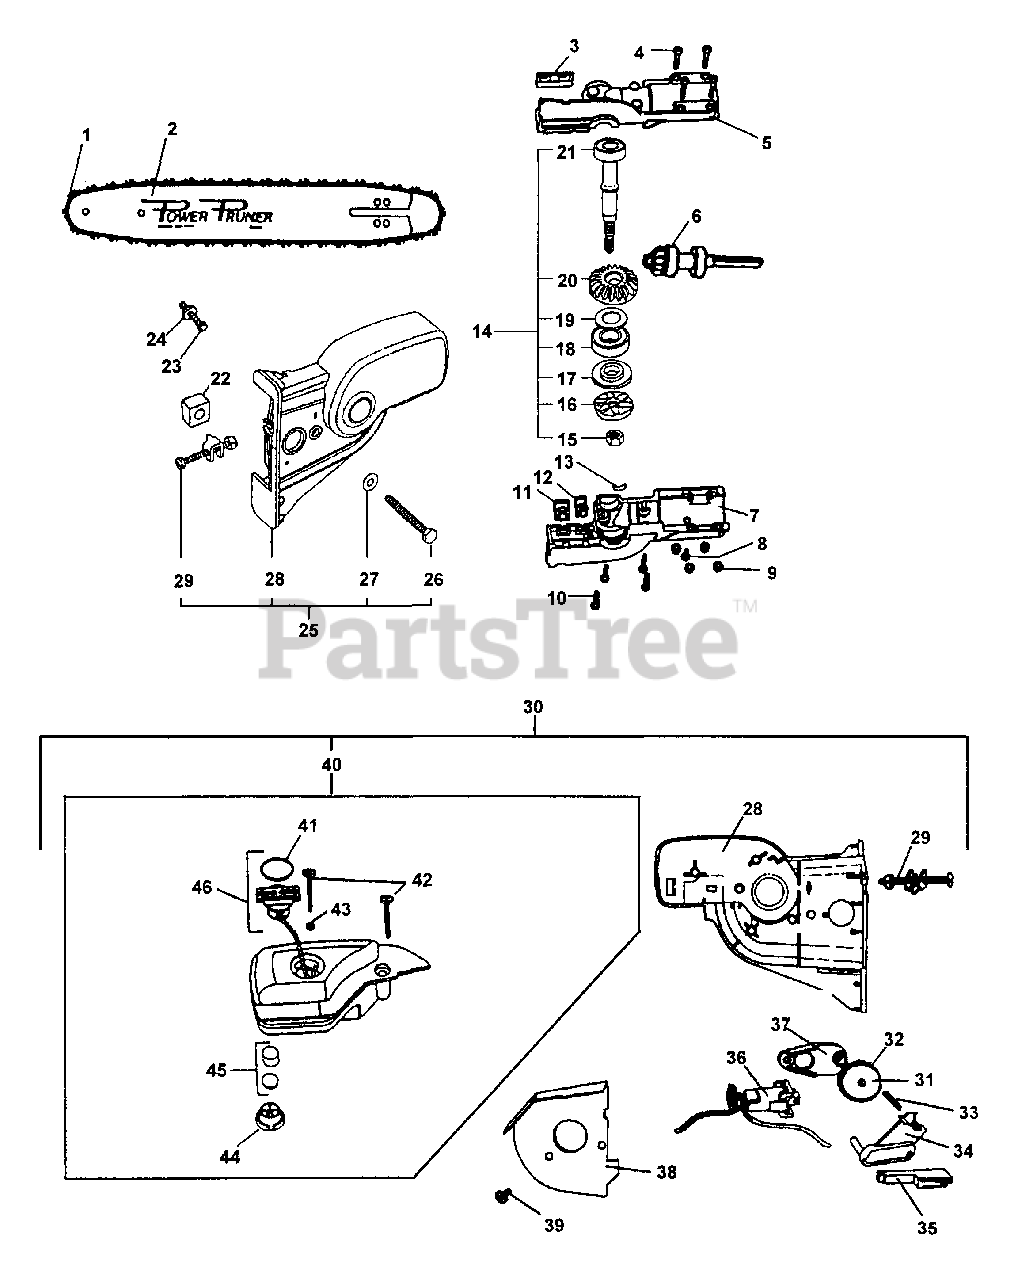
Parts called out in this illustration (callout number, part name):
1	SAW CHAIN
2	GUIDE BAR
4	SCREW, TORX 10-24 UNC 1-1/4
5	CASE, GEAR
6	SHAFT GEAR ASSY
7	CASE, GEAR
8	SCREW
9	NUT, LOCK 10-24 UNC
10	SCREW, TORX
11	SPACER
14	GEAR SHAFT ASSY
15	NUT, HEX
16	SPROCKET, DRIVE
17	SPACER, SPROCKET
18	BEARING, BALL 6001 DDU
19	WASHER 12
20	GEAR, BEVEL
21	SHAFT, GEAR
22	SPACER
23	SCREW
24	WASHER 6
25	OILER COVER ASSY
27	WASHER, FLAT
28	COVER, OILER
29	TENSIONER ASSY, CHAIN
30	AUTO-OILER ASSY
31	CAM, OIL PUMP
33	SPRING, COMPRESSION
34	LINK, OILER IDLER
36	AUTO-OILER ASSY
37	LINK, OILER DRIVE
38	PLATE, PROTECTION
39	SCREW 8-32×1/4
40	OIL TANK ASSY
42	SCREW, TORX
44	GROMMET, OIL
45	FILTER, OIL
46	CAP, OIL
